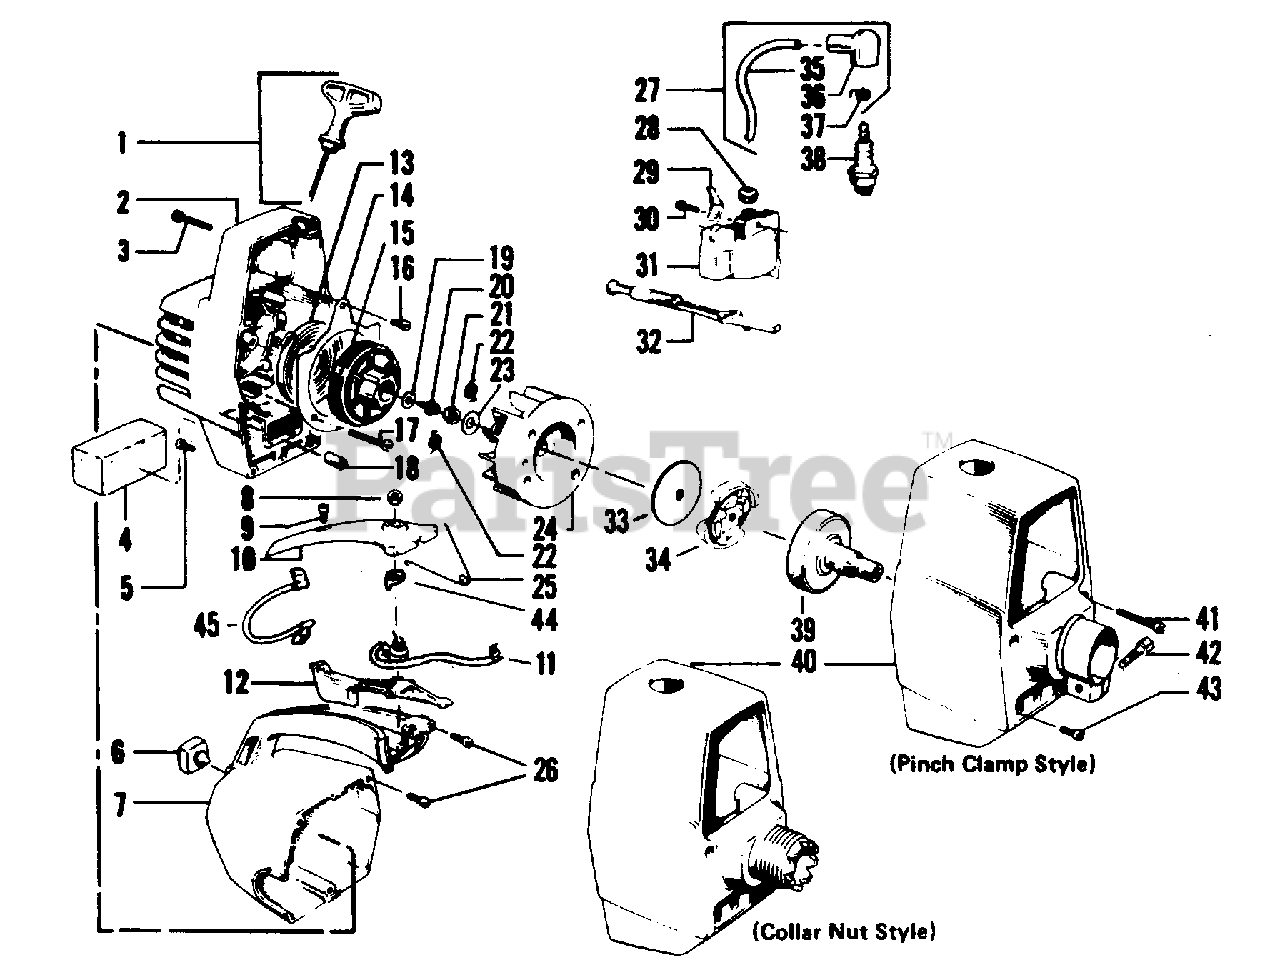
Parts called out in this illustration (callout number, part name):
2	Fan Housing Kit (Incl. 14, 16, 17, 18)
3	Screw - #10-24 x 1-1/2" - Fil. Hd.- Fan Housing Top
4	Air Filter
5	Screw - #10 - 24 x 5/8" - Fil. Hd.- Fan Housing Bottom
6	Bumper - Fuel Tank Housing
7	Handle and Fuel Tank Housing
8	Nut - Grounding Switch
9	Screw - #8 - 16 x 3/4" - Pan Hd. - Handle Cover
10	Handle Cover
11	Kit Grounding Switch (Incl. #8, 29, 44, 45)
12	Trigger - Throttle
14	Air Baffle
16	Screw - #10 - 24 x 1/4" - Fil. Hd. Air Baffle
17	Screw - #10 - 24 x 1-3/16" Fil. Hd.
19	Washer - #10 - Starter Pulley Screw
20	Screw - #10 - 24 x 1/2" - Starter Pulley
21	Nut - Flywheel
22	Spring - Starter Dog
23	Washer - Flywheel
24	Flywheel Assembly (Incl. # 22)
25	Spring - Trigger
26	Screw - #10 - 14 x 3/4" - Fan Housing to Handle and Fuel Tank
27	High Tension Lead Assembly (Inc. 35,36,37)
28	Grommet - Plug Wire
29	Electrical Tab - 45ø
30	Screw - #8 - 32 x 3/4" - Fil. Hd. - Ignition Module
31	Kit - Ignition Module
32	Choke Knob
33	Kit - Clutch Washer - See Serv. Ref. 6.
34	Kit - Clutch Assembly (Incl. Washer) - See Service Ref. 2 & 6.
35	High Tension Lead Wire
36	Boot - Spark Plug
37	Connector - Spark Plug Lead
38	Spark Plug (Champion CJ-14)
39	Drum & Coupling Assembly
40	Shroud
40	Collar Nut Style
40	Pinch Clamp Style
41	Screw - #10 - 24 x 1-1/2" - Shroud Top
43	Screw - 10 - 24 x 5/8" - Shroud Bottom
44	Washer - Grounding Switch
45	Wire - Lead Grounding Switch
